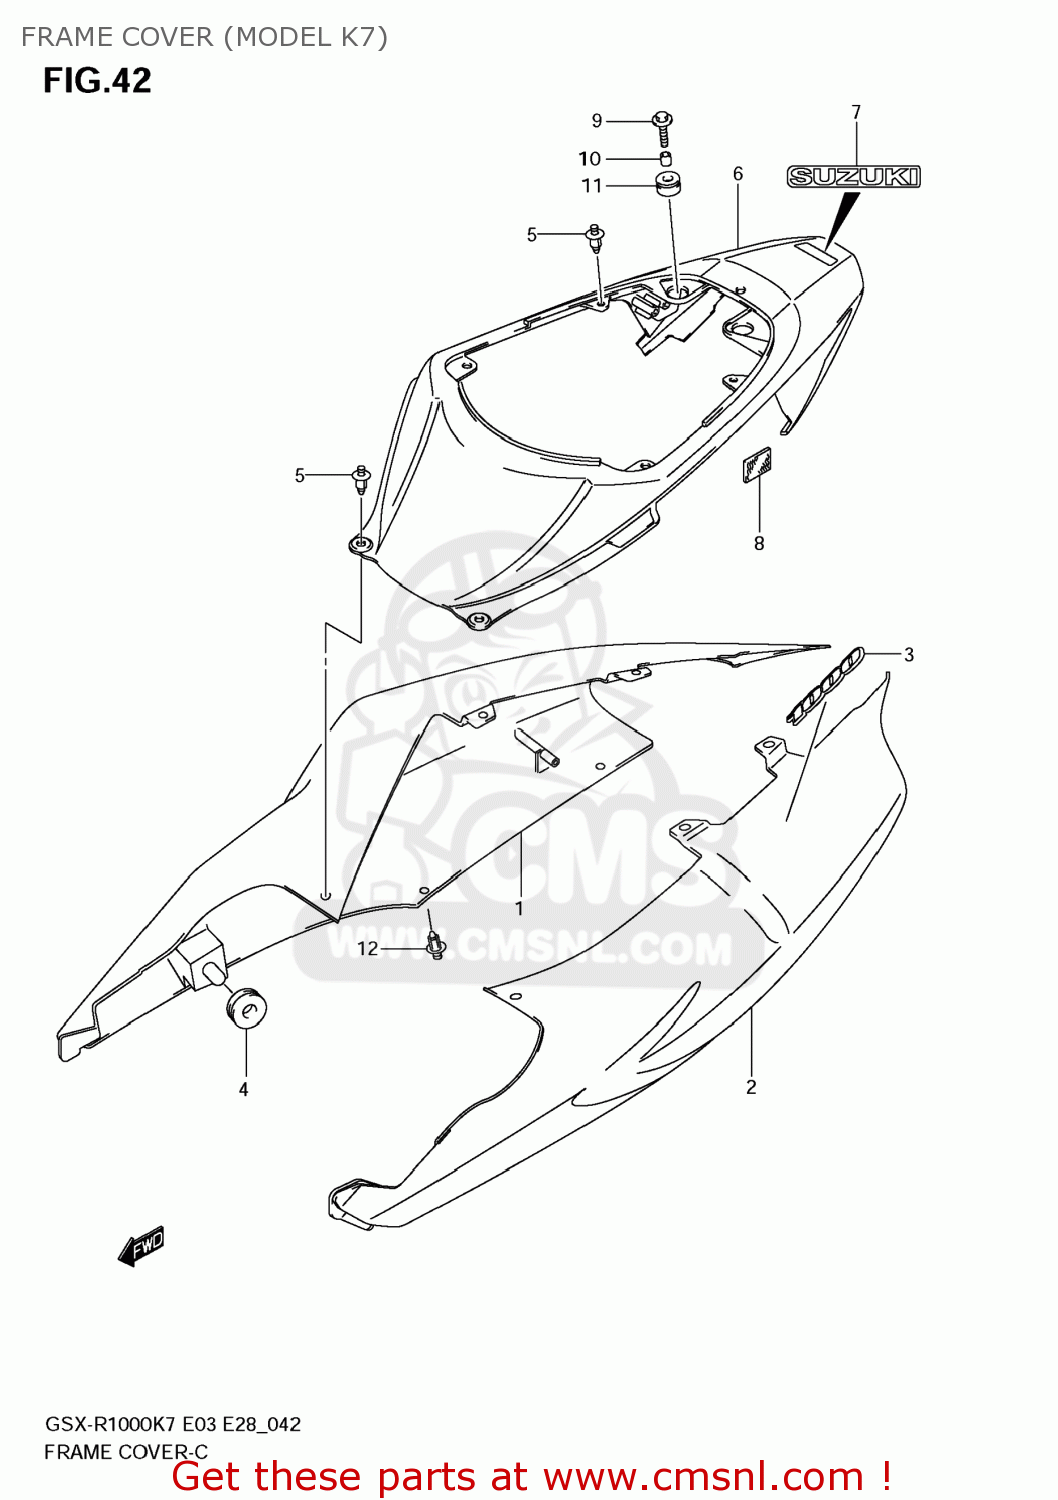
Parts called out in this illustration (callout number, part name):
1	COVER,FRAME,R(RED)
2	COVER,FRAME,L(RED)
3	EMBLEM,1000
4	CUSHION
5	CLIP(BLACK)
6	COVER,FRAME CTR
7	EMBLEM,SUZUKI
8	FASTENER
9	BOLT(6X25)
10	SPACER(6.5X10X15)
11	CUSHION
12	CLIP(BLACK)
